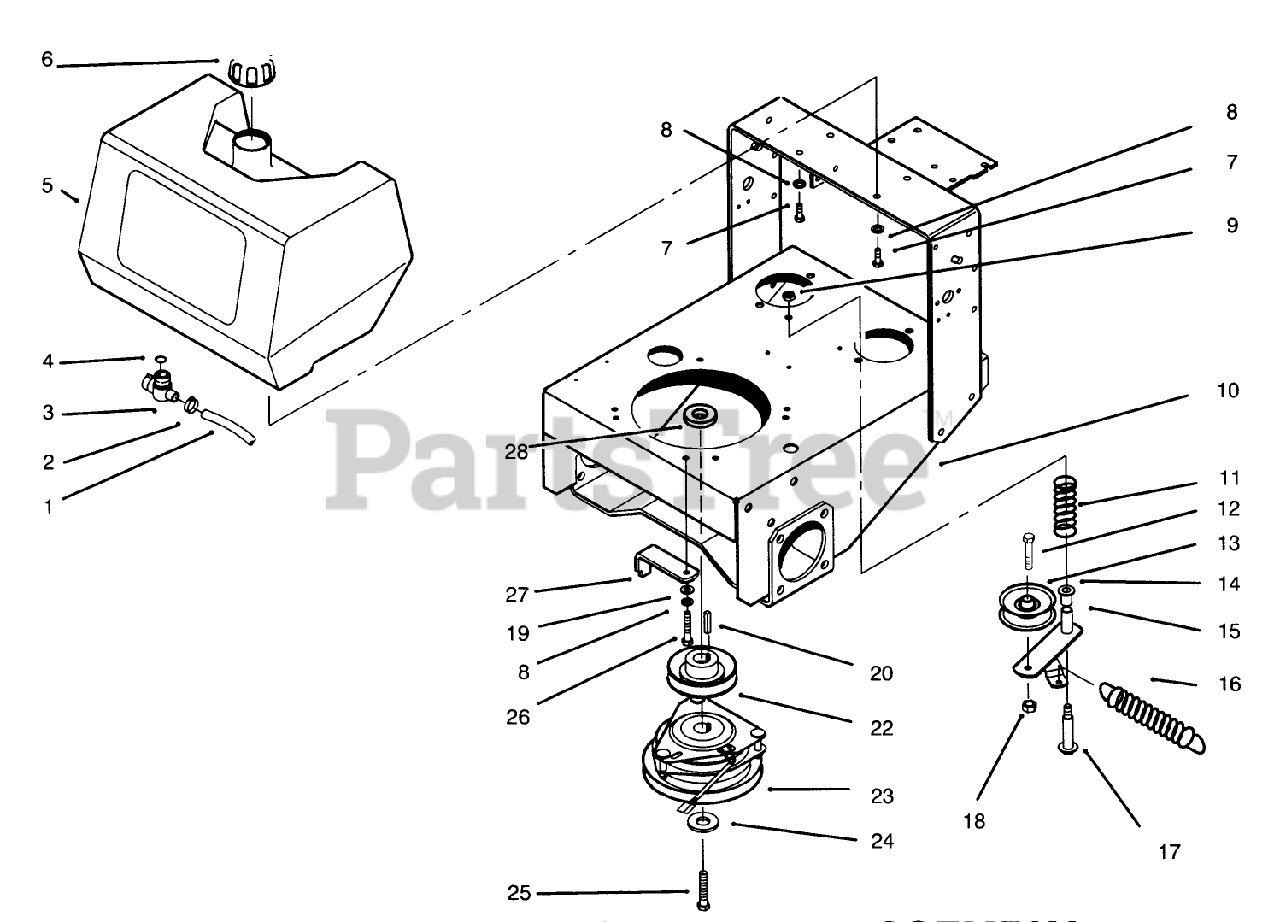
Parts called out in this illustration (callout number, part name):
1	GAS HOSE
2	CLAMP-HOSE
3	VALVE-FUEL
4	O-RING
5	FUEL TANK
6	GAS CAP ASM
7	SCREW-HH
8	WASHER-LOCK
9	NUT-LOCK
10	Frame
11	SPRING-COMPRESSION
12	SCREW-HH
13	PULLEY
14	BUSHING-FLANGE
15	Idler Asm (Incl. Ref. #14)
16	SPRING
17	BOLT-WHEEL
18	NUT-LOCK, NI
19	WASHER-PLAIN
22	Pulley
23	CLUTCH/BRAKE
24	WASHER
25	SCREW-HH
26	SCREW-HH
27	Retainer-Clutch
28	SPACER - PULLEY
